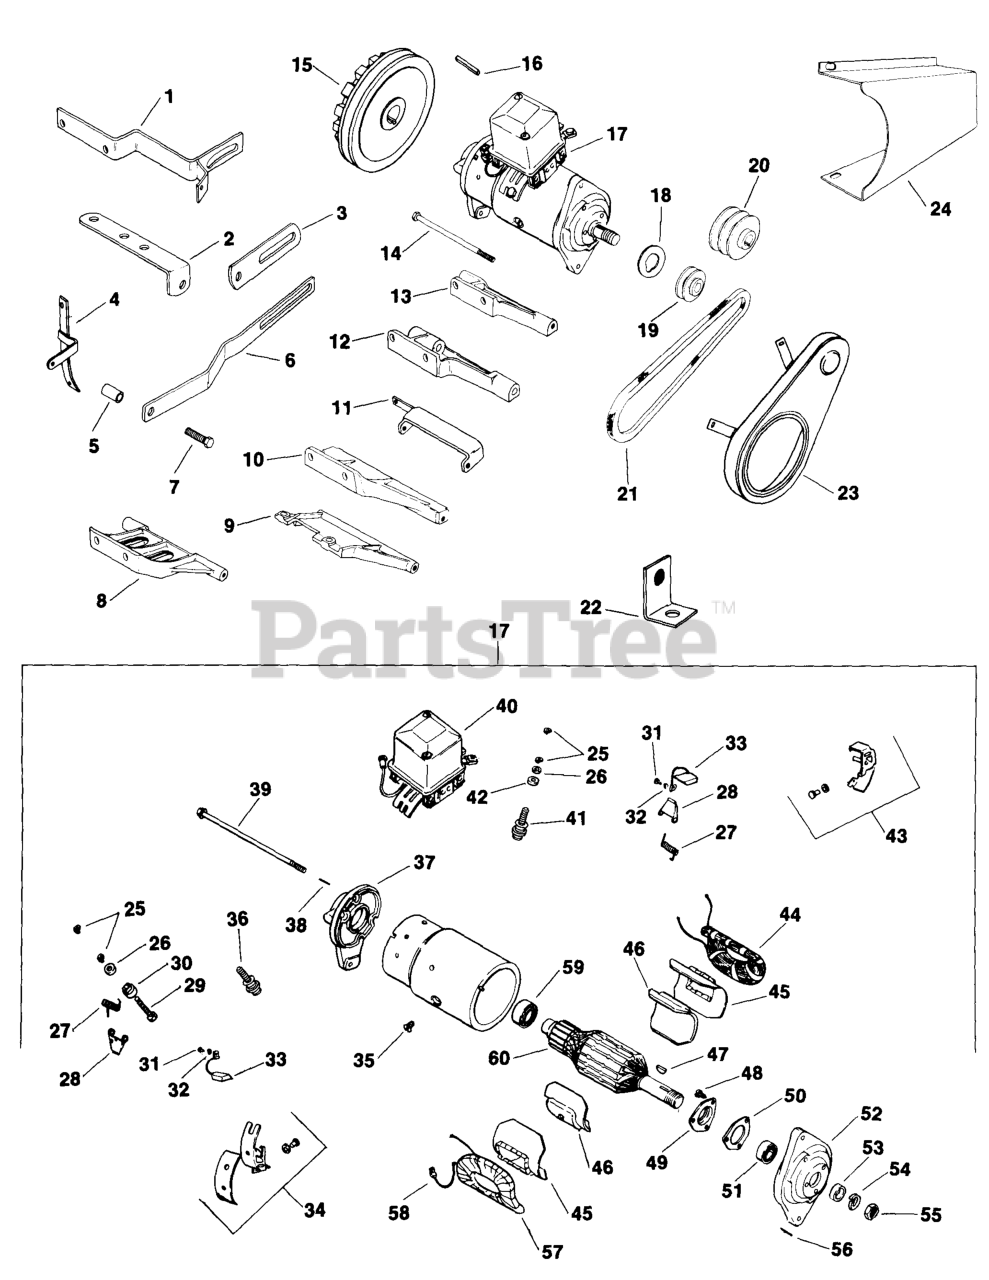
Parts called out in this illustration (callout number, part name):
2	SUPPORT - DISCONTINUED
3	BRACKET - DISCONTINUED
18	SHIM - DISCONTINUED
21	BELT - DISCONTINUED
25	WASHER - DISCONTINUED
26	WASHER, FLAT 1/4" (O.D. 1/2")
27	SPRING - DISCONTINUED
28	HOLDER - DISCONTINUED
30	BUSHING - DISCONTINUED
31	Screw, brush lead
31	SCREW, SLT PAN HD 6-32X5/16" USE 25 086 57-S
32	WASHER, SPRING LOCK #6
33	BRUSH - DISCONTINUED
34	HOLDER - DISCONTINUED
35	SCREW - DISCONTINUED
37	FRAME - DISCONTINUED
42	WASHER - DISCONTINUED
43	HOLDER - DISCONTINUED
45	INSULATOR - DISCONTINUED
46	SHOE - DISCONTINUED
47	KEY - DISCONTINUED
48	SCREW - DISCONTINUED
50	GASKET - DISCONTINUED
51	BEARING - DISCONTINUED
52	FRAME - DISCONTINUED
55	NUT - DISCONTINUED
56	PIN - DISCONTINUED
57	COIL - DISCONTINUED
58	CLIP - DISCONTINUED
